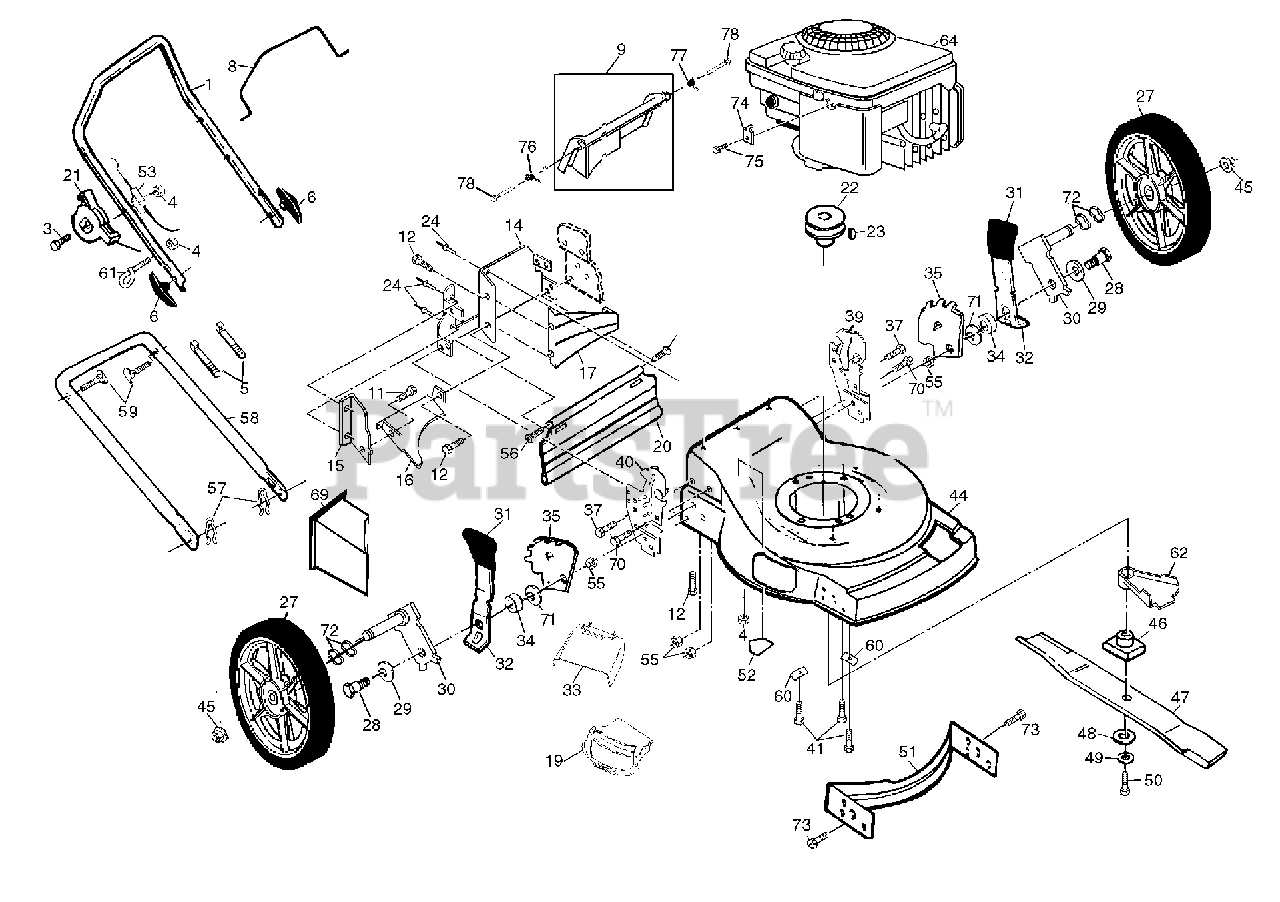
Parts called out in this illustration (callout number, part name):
1	Upper Handle
3	Hex Washer Head Screw 1/4-20 x 2-1/8
4	Locknut 1/4-20
5	Wire Tie
6	Handle Knob
8	Control Bar
9	Rear Door Kit
11	Self Tapping Screw #10-24 x 5/8
12	Hex Tapping Screw w/Sems 1/4-20 x 1/2
16	Discharge Baffle
17	Rear Baffle
19	Combi-cut Door
20	Rear Skirt
21	Throttle Control
22	Engine Pulley
23	Hi-Pro Key #505
24	Pop Rivet
27	Wheel
28	Shoulder Bolt 3/8-16 x 1-3/8
29	Spring Washer
30	Axle Arm Assembly
31	Selector Knob (Extended)
32	Selector Spring (Extended)
33	Clip-on Discharge Deflector
34	Spacer
35	Wheel Adjusting Bracket
37	Thread Cutting Screw w/Sems 5/16-18 x 3/4
39	Handle Bracket Assembly (Left)
40	Handle Bracket Assembly (Right)
41	Hex Head Thread Rolling Screw 3/8-16 x 1-1/8
44	Lawn Mower Housing
45	Flanged Locknut 3/8-16
46	Blade Adapter
47	Blade 22"
48	Hardened Washer
49	Helical Washer
50	Hex Head Machine Screw 3/8-24 x 1-3/8 Gr. 8
51	Front Baffle Kit
52	Danger Decal
53	Cable
55	Locknut 3/8-16
56	Hinge Screw 1/4-20 x 1-1/4
57	Hairpin Cotter
58	Lower Handle
59	Handle Bolt
61	Rope Guide
62	Debris Shield
69	Mulcher Plug
70	Bolt
71	Washer
72	Wave Washer
73	Screw Hx Serrated 1/4 x 20.TT
74	Clamp
75	Screw
76	Spring LH
77	Spring RH
78	Door Bolt
78	Operator's Manual (English)
78	Operator's Manual (French)
78	Repair Parts Manual
